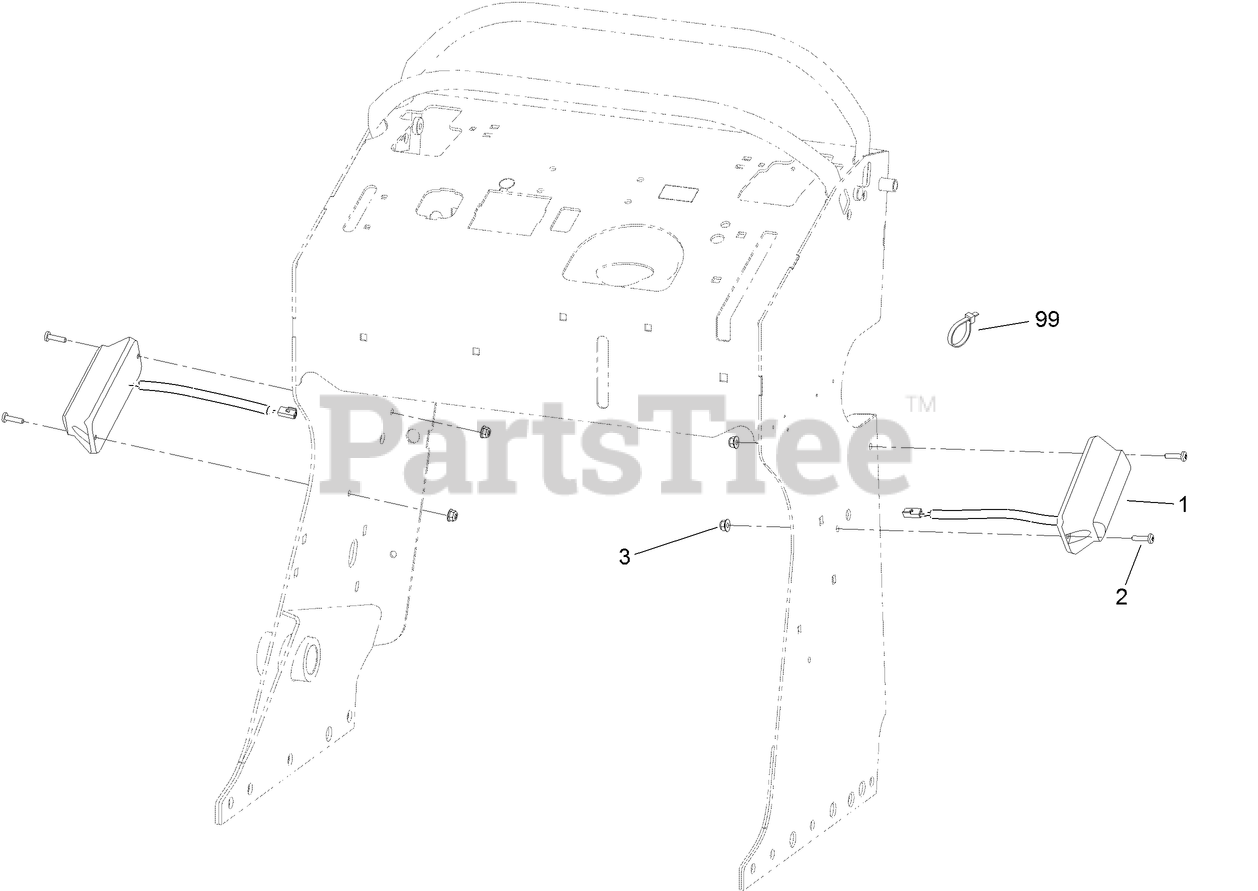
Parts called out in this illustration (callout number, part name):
1	LIGHT-STROBE ASM
2	SCREW-PPH
3	NUT-HF
99	TIE-CABLE
